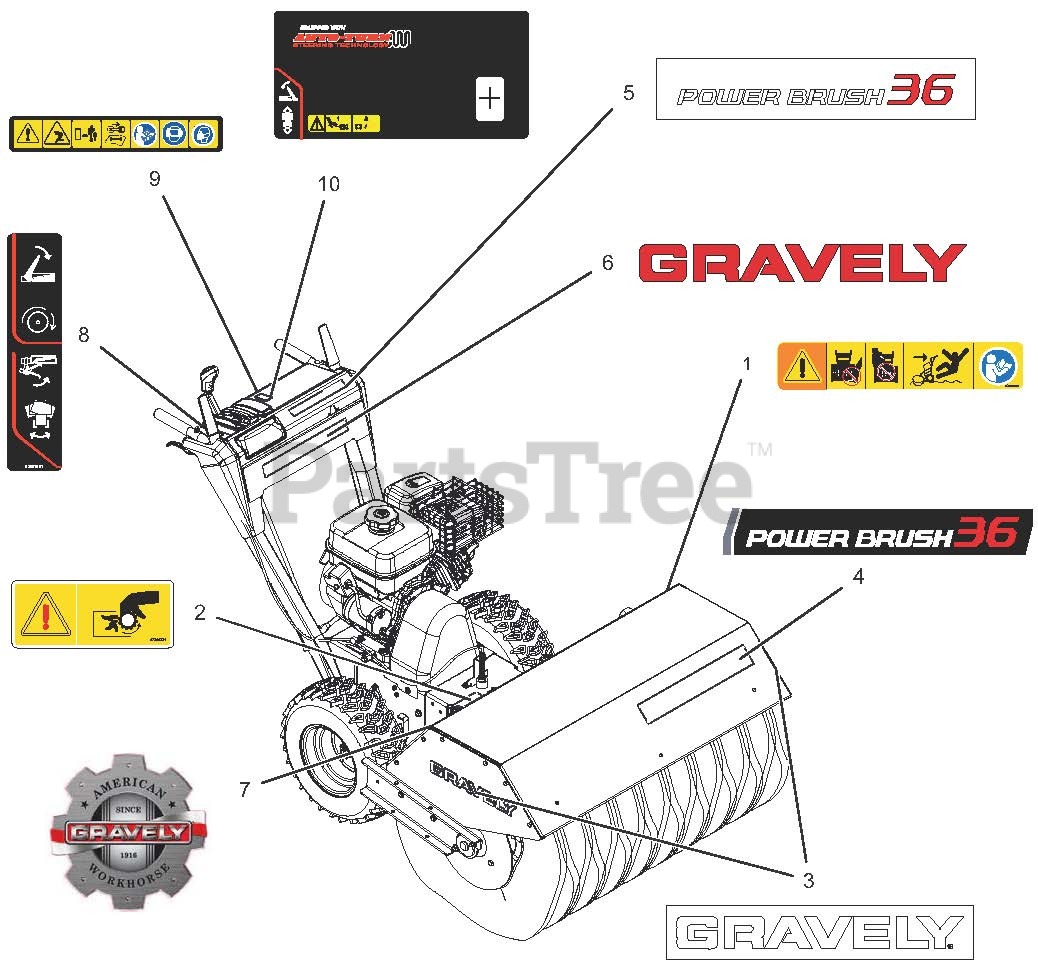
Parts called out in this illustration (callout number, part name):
1	DECAL, DANGER -POWER BRUSH-CE
2	DECAL, PTO WARNING
3	DECAL, 13.5" GRAVELY LOGO
4	DECAL,POWER BRUSH 36,GRAVELY
5	DECAL,POWER BRUSH 36,GRAVELY
6	DECAL,GRAVELY,RED,13"
7	DECAL, GRAVELY HERITAGE-LARGE
8	DECAL,CONTROL,BRUSH,RH
9	DECAL, SAFETY, DASH, BRUSH
10	DECAL, CONTROL-LRG BRUSH
